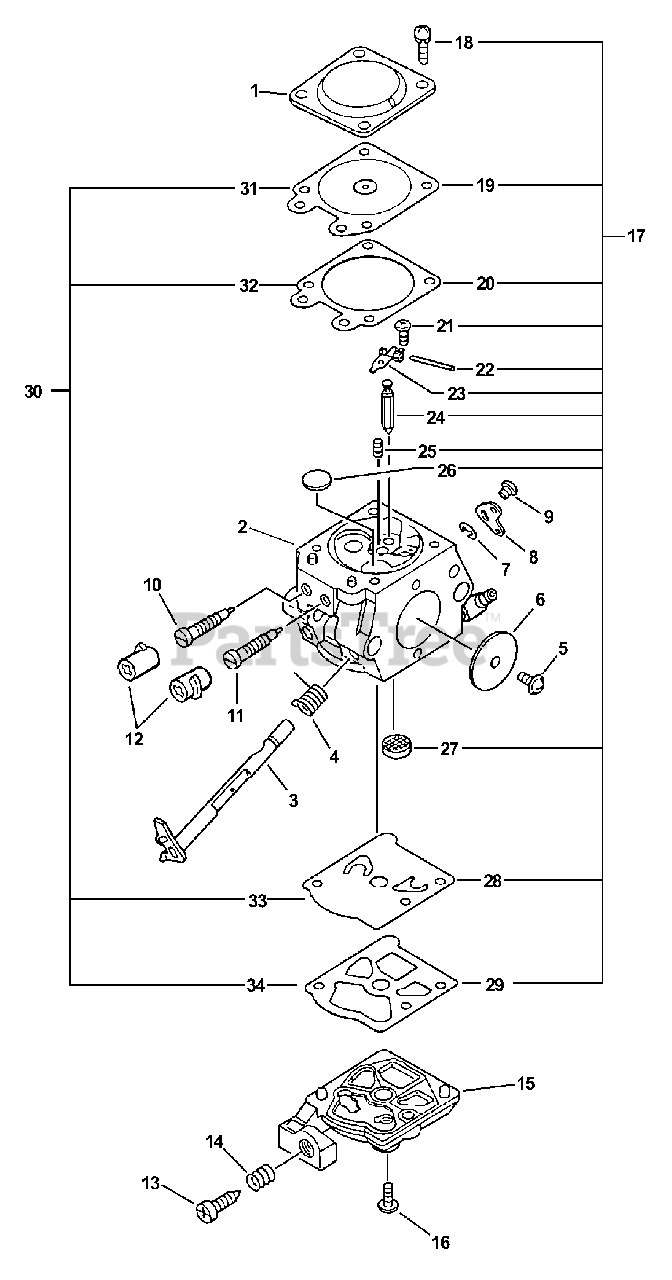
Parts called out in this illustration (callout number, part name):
1	COVER, METERING
2	BODY, CARBURETOR
3	SHAFT, THROTTLE
4	SPRING, THROTTLE RETURN
6	VALVE, THROTTLE
7	RING, RETAINING
8	LEVER, THROTTLE
10	NEEDLE - HIGH SPEED
11	NEEDLE - LOW SPEED
12	CAP, LIMITER
13	SCREW, IDLE ADJUST
14	SPRING, IDLE ADJUST
15	COVER, PUMP
16	SCREW, PUMP COVER
17	REPAIR KIT
18	SCREW, METERING COVER
19	DIAPHRAGM, METERING
20	GASKET, METERING
21	SCREW, METERING LEVER PIN
22	PIN, METERING LEVER
23	LEVER, METERING
24	VALVE, INLET NEEDLE
25	SPRING, METERING LEVER
26	PLUG, WELCH
27	STRAINER
28	DIAPHRAGM, PUMP
29	GASKET, PUMP
30	DIAPHRAGM/GASKET KIT
31	DIAPHRAGM, METERING
32	GASKET, METERING
33	DIAPHRAGM, PUMP
34	GASKET, PUMP
